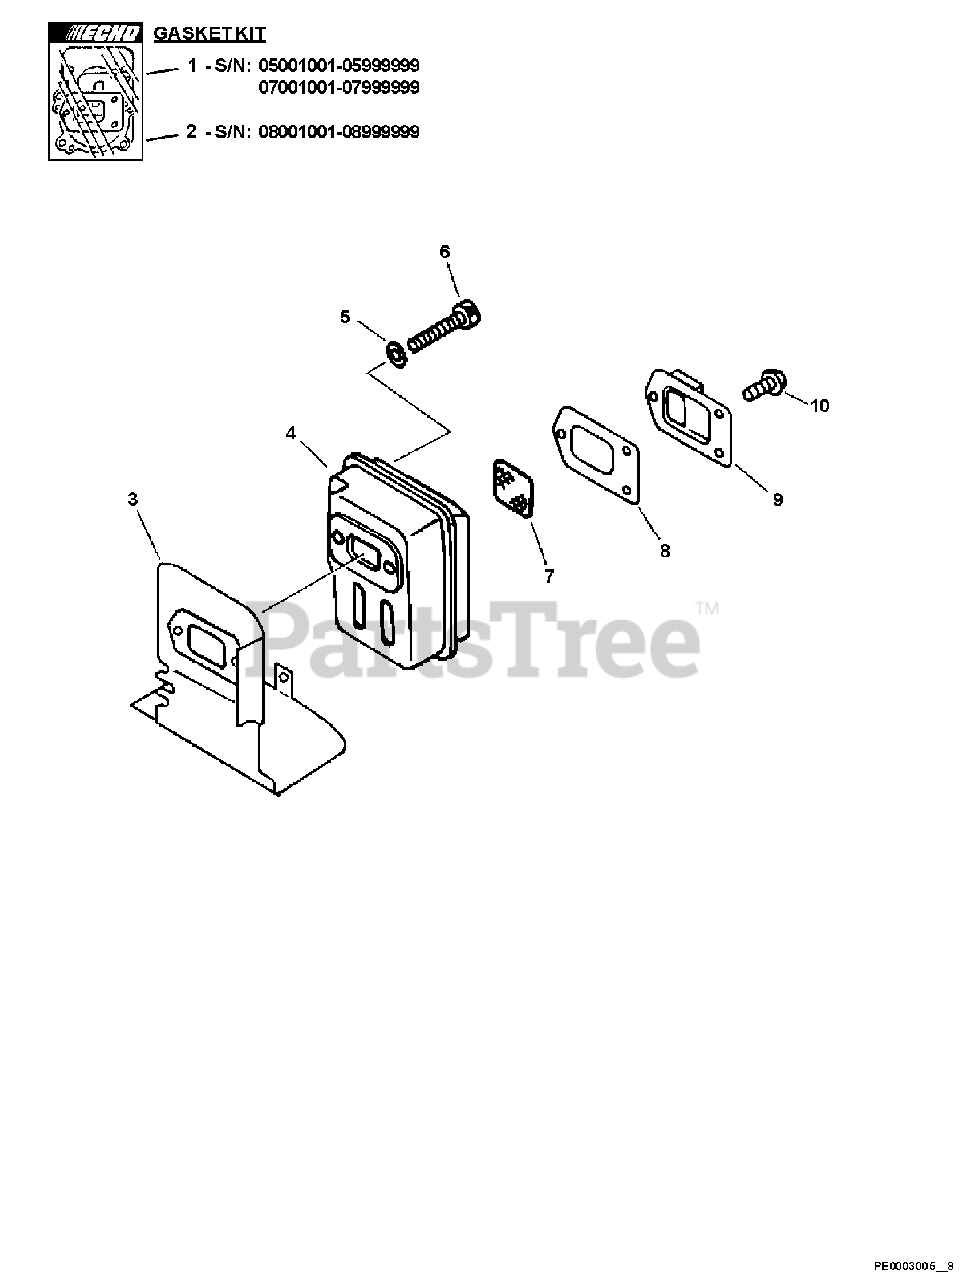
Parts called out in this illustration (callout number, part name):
1	GASKET KIT
2	GASKET KIT
3	SHIELD, EXHAUST
5	WASHER - 5
6	SCREW - 5X55
7	SCREEN, SPARK ARRESTOR
8	GASKET, EXHAUST
9	GUIDE, EXHAUST
10	SCREW - 4X10
